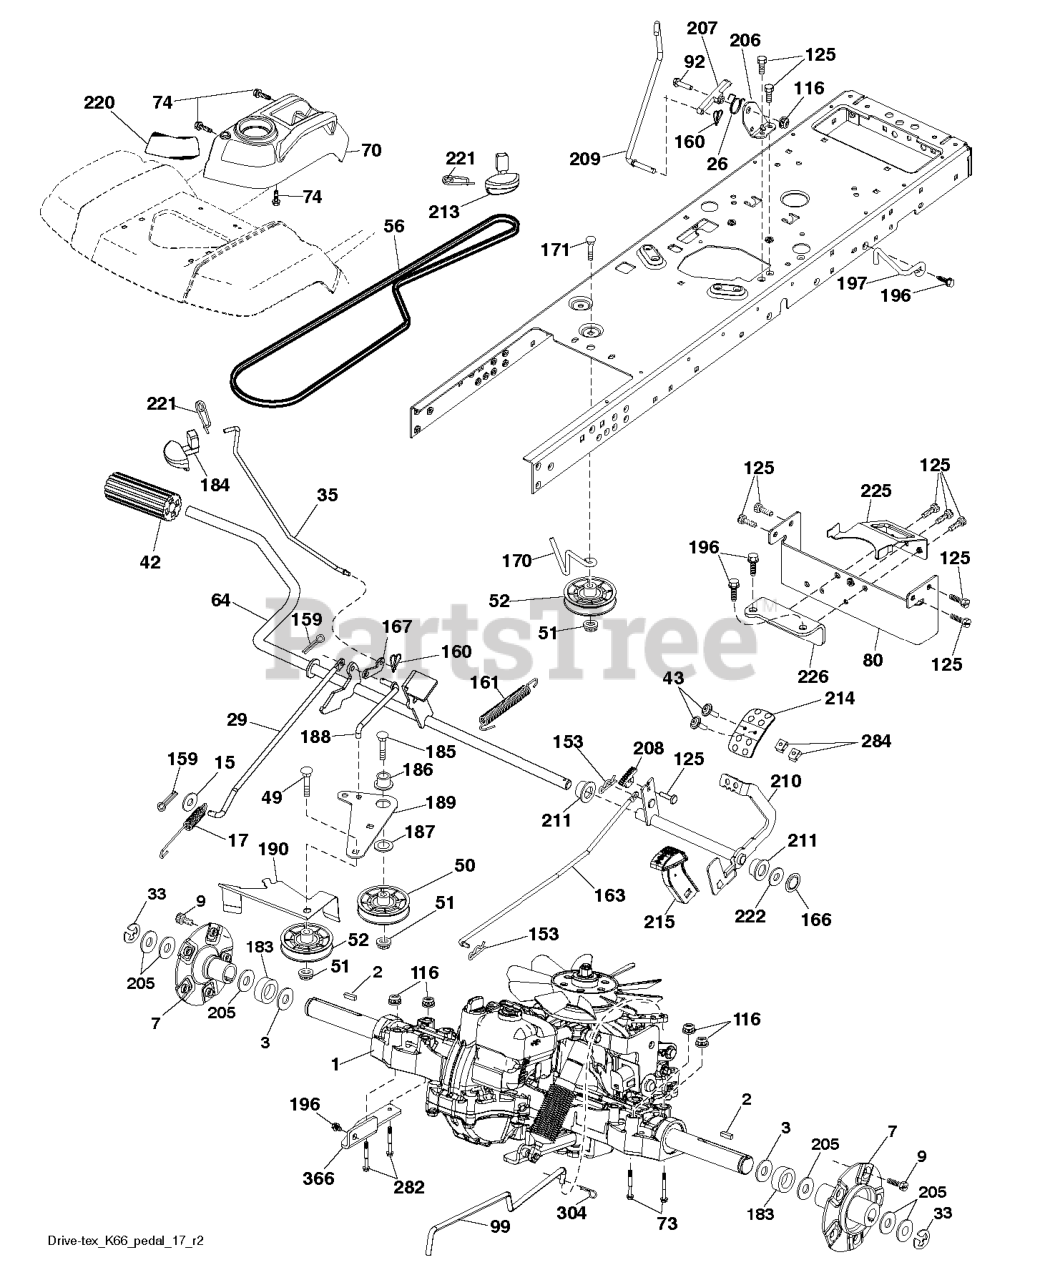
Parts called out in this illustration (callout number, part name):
2	KEY 1/4 X 2.5
7	HUB.ASM.WHEEL.REAR.23"TEX
9	HUB BOLT
15	WASHER
17	SPRING.BRAKE.K46
26	SPRING.RETURN.CRUISE
29	ROD.BRAKE.K66
33	E RING HYT
35	ROD .BRAKE. PARKING. GT. HUSQ.
42	PEDAL COVER T
43	SCREW.MACHINE.CR.1/4-20
50	IDLER.FLAT.910.OFFSET
51	NUT LOCK FLG 3/8-16 UNC
52	IDLER.V-GROOVE.910.OFFSET
64	SHAFT.ASM.PEDAL.BRK.CNTR
70	CONSOLE.ASM.RH.GT.FC.HUSQ
73	BOLT HEX 5/16-18 GR 5
74	SCREW.HI-LO.CONSOLE
80	TORQUE.STRAP.PNT.BLACK
92	BOLT
99	ROD.SPRING.BYPASS.K66.GT.Z
116	NUT LOCK HEX FLANGE 5/16-18
125	SCREW
153	RETAINER M
159	COTTER PIN
160	RETAINER CLIP
161	SPRING, RETURN LT
163	ROD.PEDAL.CONTROL
166	NUT.PUSH.625
167	LATCH.BRAKE.SPRING
170	KEEPER.V-IDLER.CENTER.
171	BOLT
183	SPACER.AXLE.HG.TEX
184	RB HANDLE.PARKG.BRK.HUS/PRED
186	SPACER.RETAINER
187	WASHER 12/32X2X10GA
188	RP.LINK.CLUTCH.GROUND.DRIVE
189	BELLCRANK.GROUND.DRIVE.TEX.
190	KEEPER.BELLCRANK.DRIVE
196	SCREW 3/8-16X1
197	BRKT.ANIT-ROTATION.CLUTCH
206	BRACKET.MOUNT.CRUISE.LATCH
207	LATCH.CONTROL.CRUISE
208	GEAR.SECTOR.CONTROL.CR
209	ROD.CONTROL.CRUISE.GT.
210	ROCKER.ASM.PEDAL.CONTR
211	BEARING.NYLON
213	KNOB.CONTROL.CRUSIE.HU
214	PEDAL.FORWARD.HUSQVARNA.DEALER
215	PEDAL RUBBER REVERSE
220	REFLECTOR.RH.TEX GT
221	RETAINER.SPRING.CLIP.H
222	WASHER 21/32 X 1-1/4 X 10 GA.
225	KEEPER.BELT.TRANSAXLE.K66
226	BRACKET.MOUNT.TORQUE.K66.TG
282	BOLT HEX FLGHD 5/16-18X3 GR. 5
284	NUT.U-CHNL.1/4-20.550DP.350PNL
366	BRACKET.REINFORCEMENT
